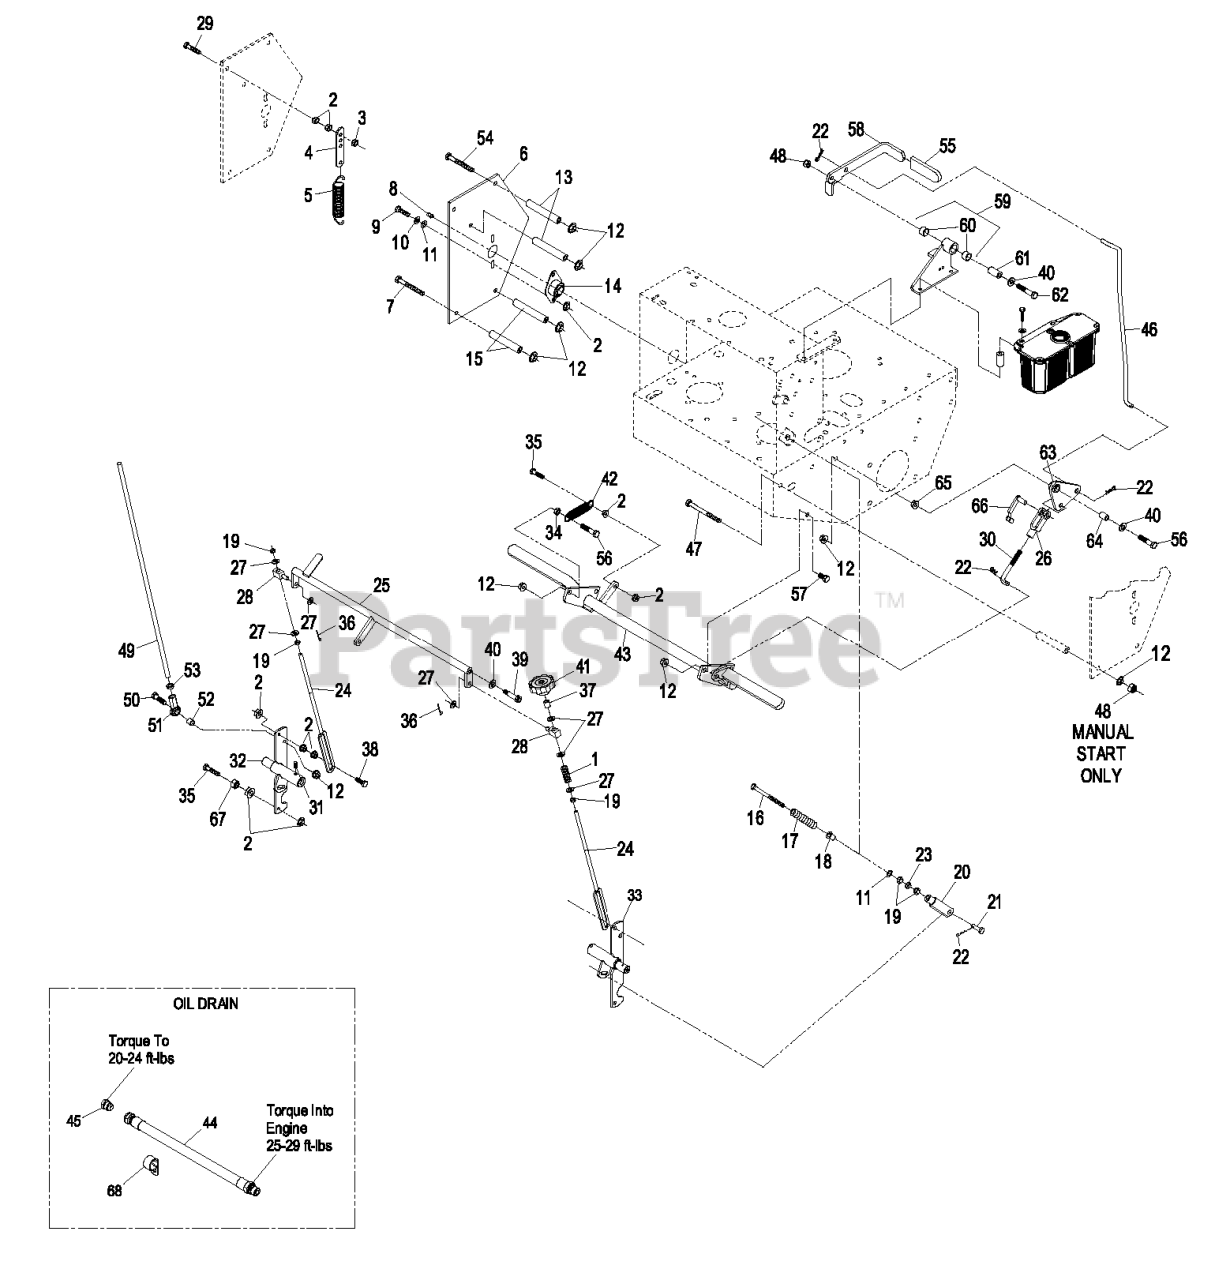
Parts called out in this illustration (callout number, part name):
1	SPRING-COMPRESSION
3	NUT-LOCK, NI
4	TAB-SPRING, EXTENSION
5	SPRING-EXTENSION
6	SHIELD-CONTROL
7	SCREW-HH
8	FITTING-GREASE
9	SCREW-HH
10	WASHER-LOCK
11	WASHER-FLAT
12	NUT-HHF, WHIZ
13	SPACER-SHIELD
14	BEARING-FLANGE, SIDE
15	SPACER-SHIELD
16	BOLT-RETURN, NEUTRAL
17	SPRING,COMPRESSION (NEUT)
18	BUSHING-FLANGED
19	NUT-HEX
20	YOKE-ADJUSTABLE
21	PIN-CLEVIS
22	PIN-COTTER
23	NUT-JAM
24	LINK-CONTROL, SPEED
25	CRANK-CONTROL, SPEED
26	YOKE-LINKAGE, BRAKE
27	WASHER-PLAIN
29	BOLT-TAP, HH
30	LINKAGE-LOWER
31	SCREW-SET
32	SHAFT-CONTROL, LH
33	SHAFT-CONTROL, RH
34	NUT-JAM
35	SCREW-HH
36	PIN-COTTER
38	SCREW-HH
39	SCREW-HSH
40	WASHER-FLAT
41	KNOB-TRACKING
42	SPRING-IDLER
46	LINKAGE,UPPER- TTHP
47	SCREW-HH
48	NUT-LOCK, NI
49	LINK,DRIVE (PLTD)
50	SCREW-HH
51	JOINT-BALL END, LH
52	SPACER-TUBE, PUMP LINK
53	NUT-HEX JAM, LH
54	SCREW-HH
55	GRIP-LEVER
56	SCREW-HH
57	SCREW-HH
58	LEVER,PARK BRK W/DECAL
59	BRACKET ASM
60	SLEEVE-BUSHING
61	BUSHING-PIVOT
62	SCREW-HH
63	BELLCRANK ASM
64	BUSHING-PLASTIC
66	PIN-SPRING, CLEVIS
67	NUT-JAM
68	CLIP-LOOM
